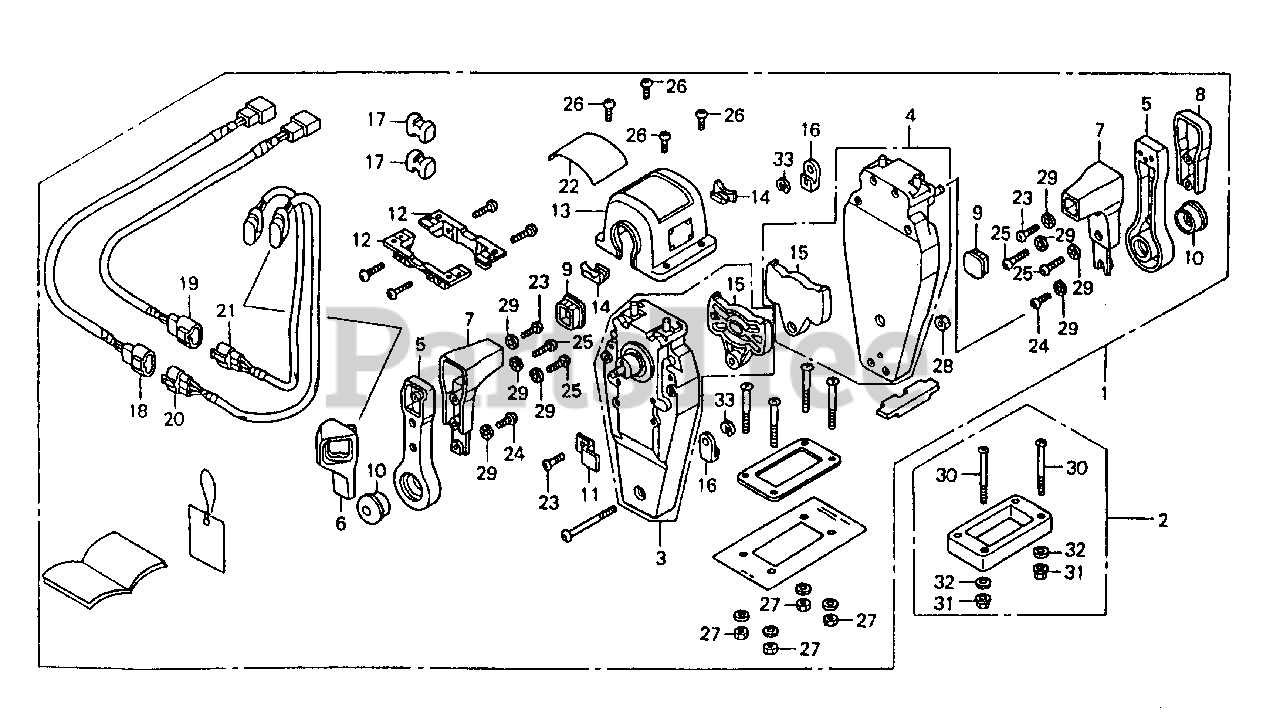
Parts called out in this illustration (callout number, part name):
1	BOX KIT, R. REMOTE CONTROL
2	SPACER, TOP DUAL
3	HOUSING ASSY., L. (INNER)
4	HOUSING ASSY., R. (INNER)
5	HANDLE, REMOTE CONTROL
6	COVER, L. GRIP
7	GRIP, REMOTE CONTROL HANDLE
8	COVER, DUAL GRIP
9	CAP, GRIP
10	BUTTON, THROTTLE
11	PLATE, CABLE CLAMP
12	BRACKET, REMOTE CONTROL
13	HOUSING, DUAL REMOTE CONTROL
14	HOUSING, LEAD
15	PLATE, DWELL
16	CABLE, TERMINAL
17	SPACER, CABLE CLAMP
18	SUB-HARNESS A ASSY., POWER
19	SUB-HARNESS B ASSY., POWER
20	SWITCH ASSY., POWER TRIM-TILT
21	SWITCH ASSY., POWER TRIM-TILT
22	MARK, REMOTE CONTROL (DUAL)
23	SCREW, PAN (5X16)
24	SCREW, PAN (5X10)
25	SCREW, PAN (5X20)
26	SCREW, PAN (4X10)
27	NUT, HEX. (5MM)
28	NUT, HEX. (5MM)
29	WASHER, LOCK (5MM)
30	SCREW, PAN (5X65)
31	NUT, FLANGE (5MM)
32	WASHER, PLAIN (5MM)
33	E-RING (6MM)
